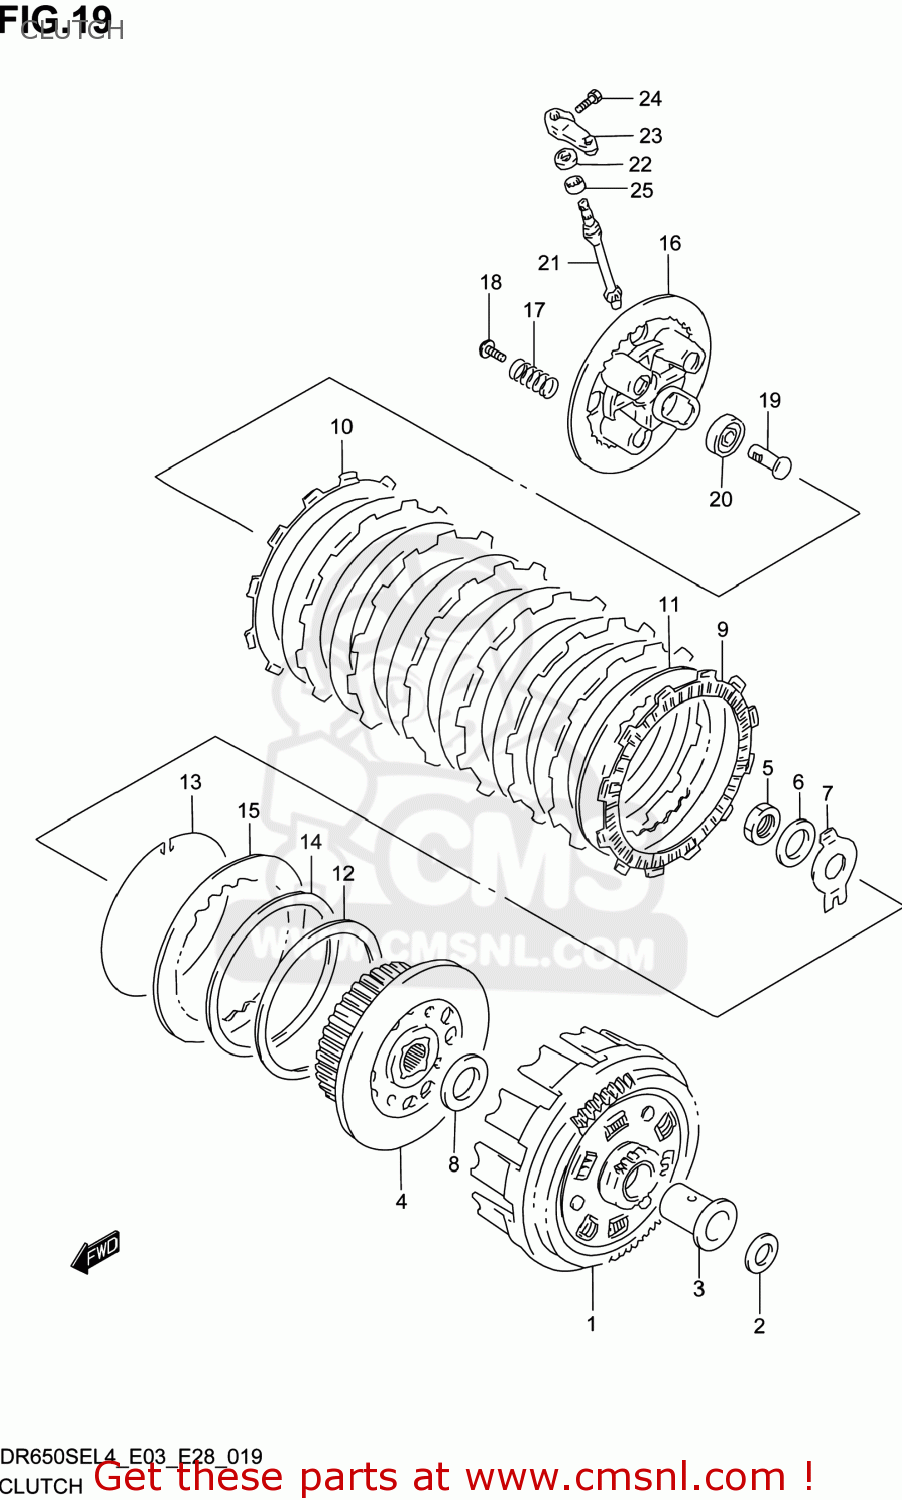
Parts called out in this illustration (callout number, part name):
1	GEAR ASSY,PRI DRIVEN
2	WASHER(22X32X3)
3	SPACER,PRIMARY DRIVEN GEAR
4	HUB,CLUTCH SLEEVE
5	NUT
6	WASHER
7	WASHER
8	WASHER(22X44X2)
9	PLATE,CLUTCH DRIVE (NAS)
10	PLATE,CLUTCH DRIVE (NAS)
11	PLATE,CLUTCH DRIVEN NO.1 (NAS)
12	SEAT,WAVE WASHER
13	RING,STOPPER
14	WASHER
15	PLATE,CLUTCH DRIVEN (NAS)
16	DISC,CLUTCH PRESSURE
17	SPRING
18	BOLT(6X16)
19	RACK,CLUTCH RELEASE
20	BEARING
21	PINION,CLUTCH RELEASE
22	SEAL,OIL(10X17X5)
23	ARM,CLUTCH RELEASE
24	BOLT
25	BEARING(12X16X10)
